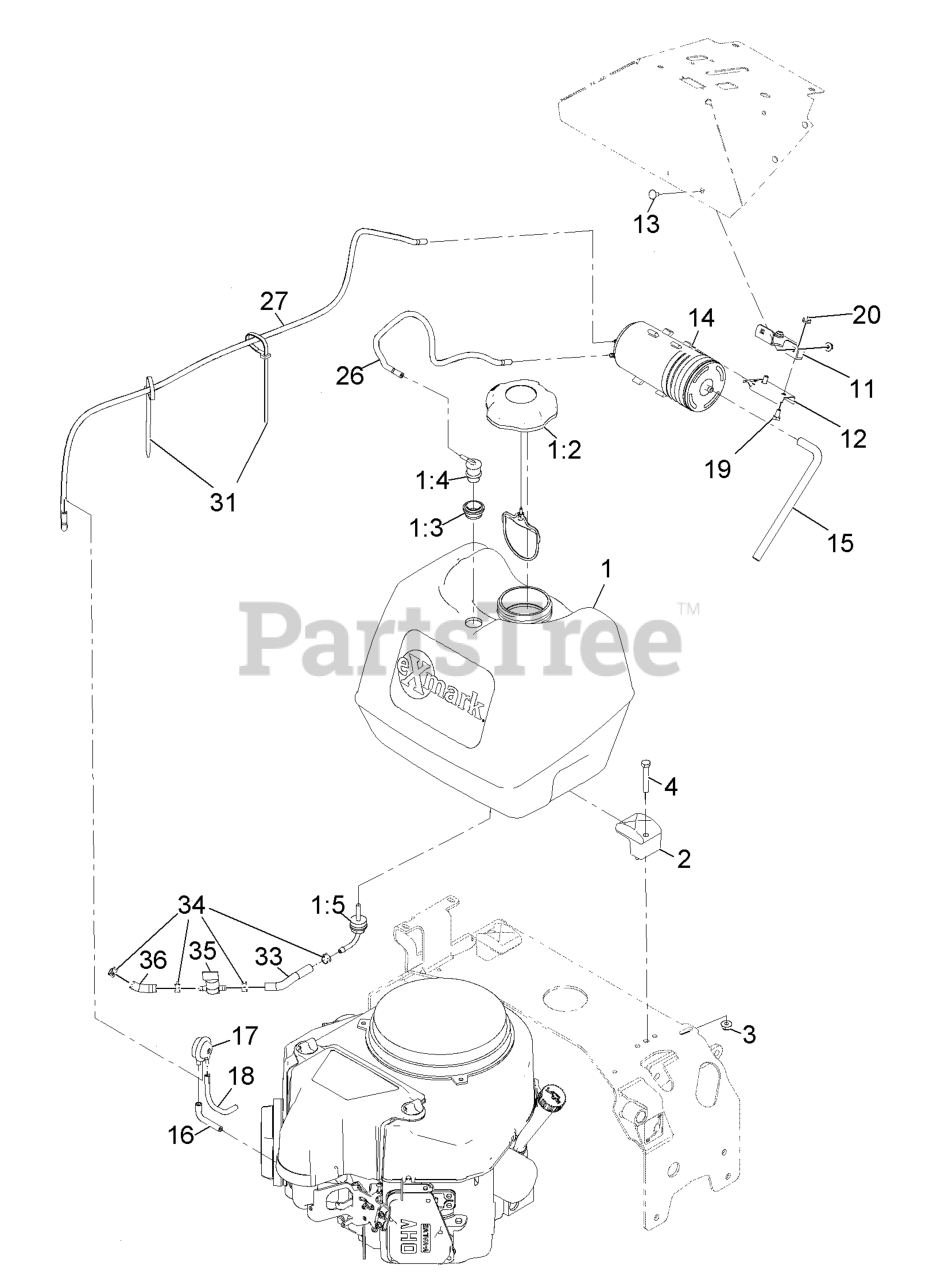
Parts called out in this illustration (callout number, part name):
1	ASM, FUEL TANK
1:3	GROMMET
1:4	VALVE-VENT, FUEL
1:5	FITTING-FUEL, BULKHEAD
3	NUT-HF, NI
4	SCREW-HH
11	BRACKET-CANISTER, CARBON
12	BRACKET-CANISTER, CARBON
13	SCREW-CARR
14	CANISTER-CARBON, 800CC
15	HOSE-VENT, CANISTER
16	HOSE-VENT, FORMED
17	VALVE-CONTROL, VACUUM
18	HOSE-VENT, FORMED
19	SCREW-HH
26	HOSE-VENT
27	HOSE-VENT, FORMED
31	TIE-PLASTIC
33	HOSE-FUEL
34	CLAMP-HOSE
35	VALVE-FUEL
36	HOSE-FUEL
